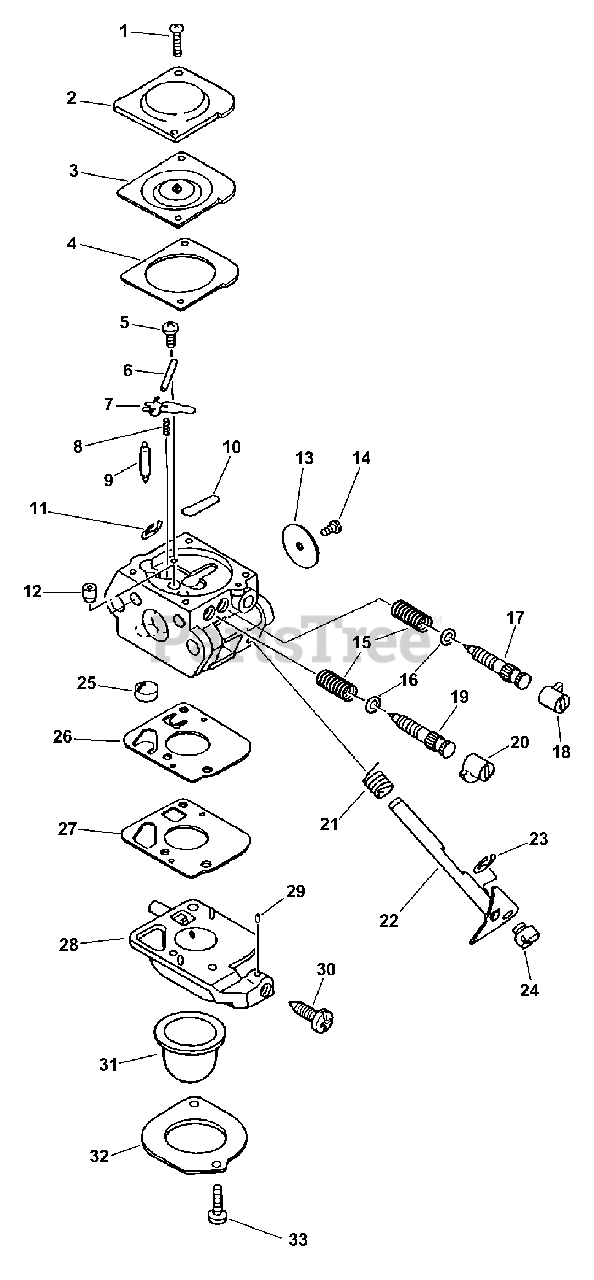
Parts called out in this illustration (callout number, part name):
1	SCREW
2	COVER, METERING
3	DIAPHRAGM, METERING
4	GASKET, METERING
5	SCREW, METERING LEVER PIN
6	PIN, METERING LEVER
7	LEVER, METERING
8	SPRING, METERING LEVER
9	VALVE, INLET NEEDLE
10	PLUG, WELCH
11	RING, RETAINING
12	NOZZLE, CHECK VALVE
13	VALVE, THROTTLE
14	SCREW
15	SPRING
16	WASHER
17	NEEDLE - LOW SPEED
18	CAP, LIMITER
19	NEEDLE - HIGH SPEED
20	CAP, LIMITER
21	SPRING, RETURN
22	SHAFT, THROTTLE
23	RING, RETAINING
24	SWIVEL
25	STRAINER
26	DIAPHRAGM, PUMP
27	GASKET, PUMP
28	BASE, PURGE
29	PIECE, FRICTION
30	SCREW, IDLE ADJUST
31	BULB, PURGE
32	RETAINER, PURGE BULB
33	SCREW, RETAINER
